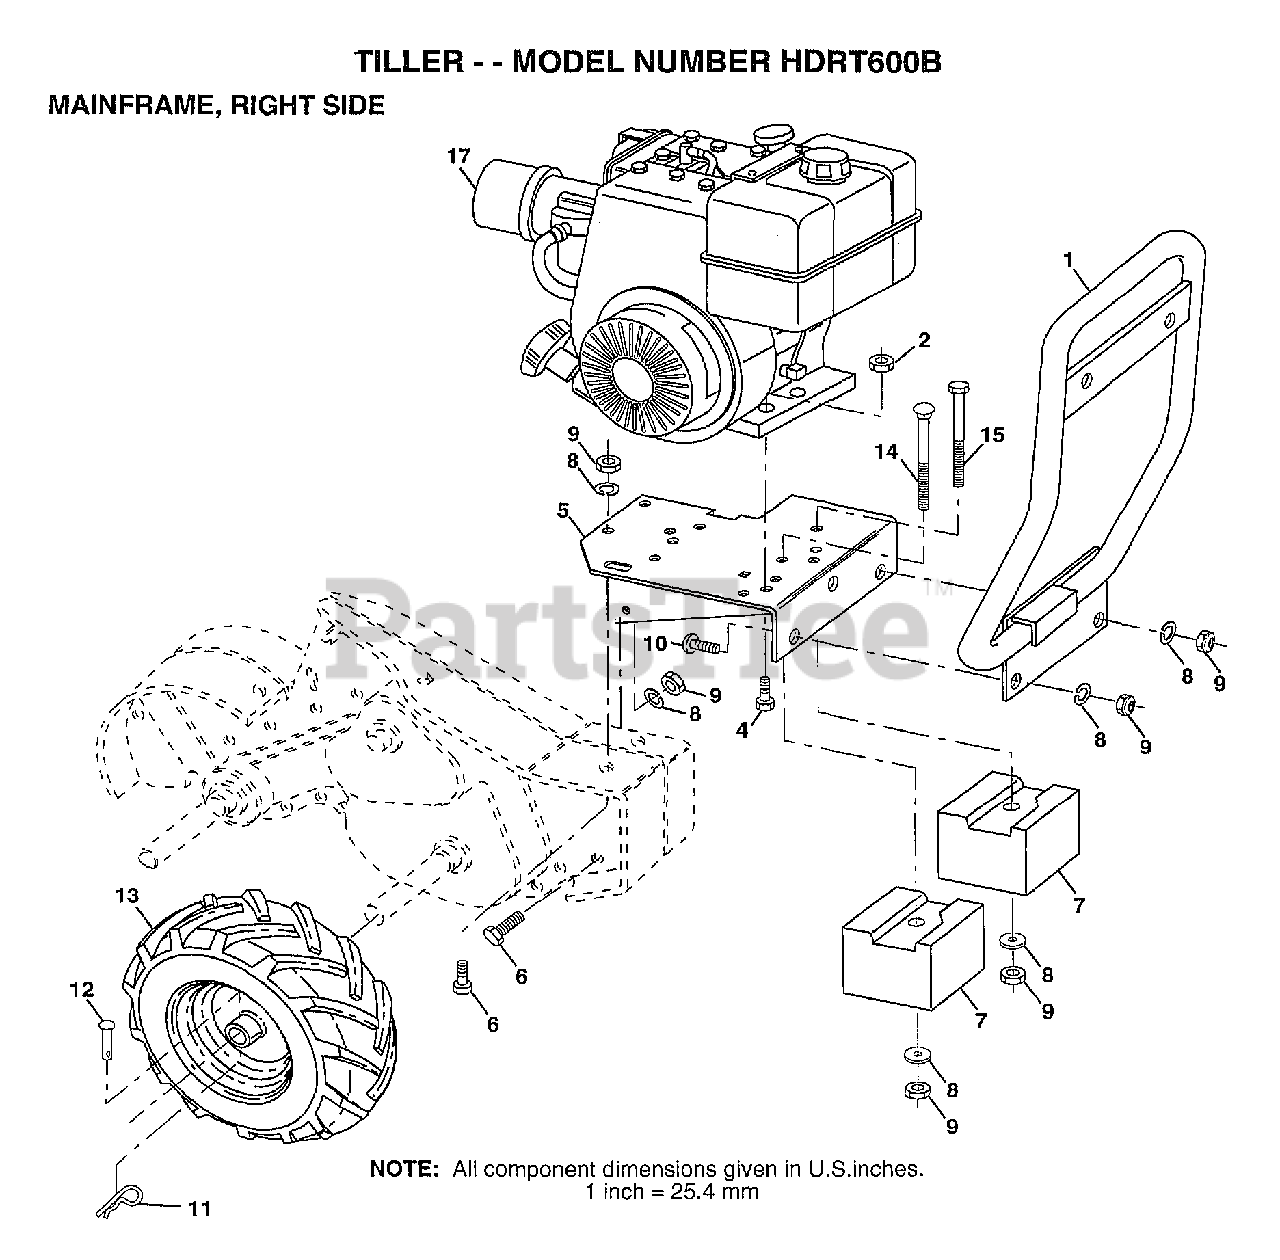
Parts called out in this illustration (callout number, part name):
1	BUMPER.ASM
4	BOLT
5	"ASM. ENGINE, BASE"
6	BOLT
7	COUNTERWEIGHT CRT
8	LOCKWASHER
9	NUT.HEX.3/8-16UNC
11	SPRING.RETAINER
12	RIVET.PAN HD.1.75
13	TIRE TI
13	RIM.16X4X8.WHT
14	BOLT CRT
15	BOLT.3/8-16X4.5
